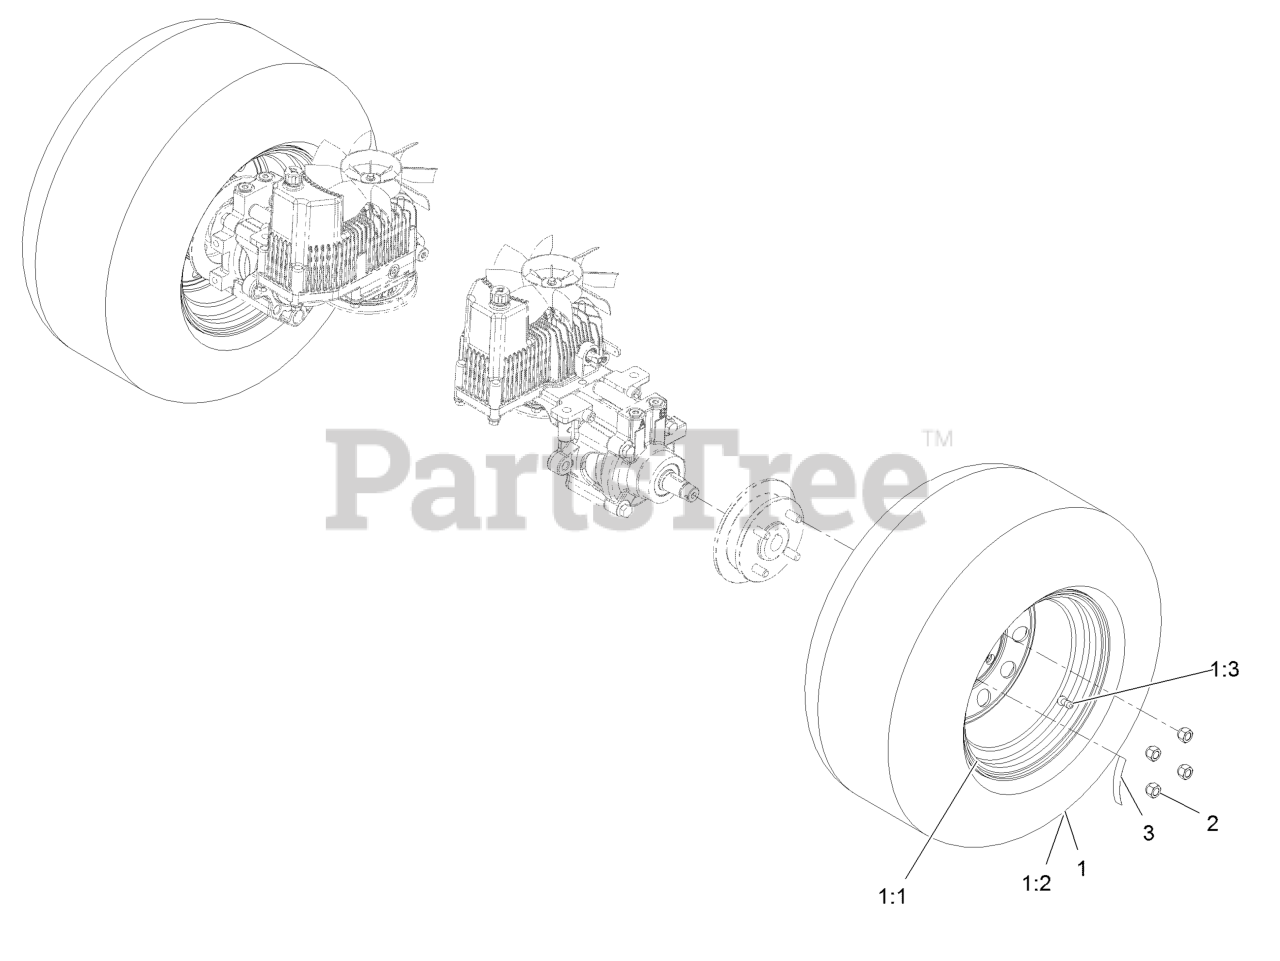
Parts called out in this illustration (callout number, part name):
1	Wheel And Tire ASM
1:3	Stem-Valve
2	Nut-Lug 1/2-20
3	Decal-Torque, Wheel Hub Lug
